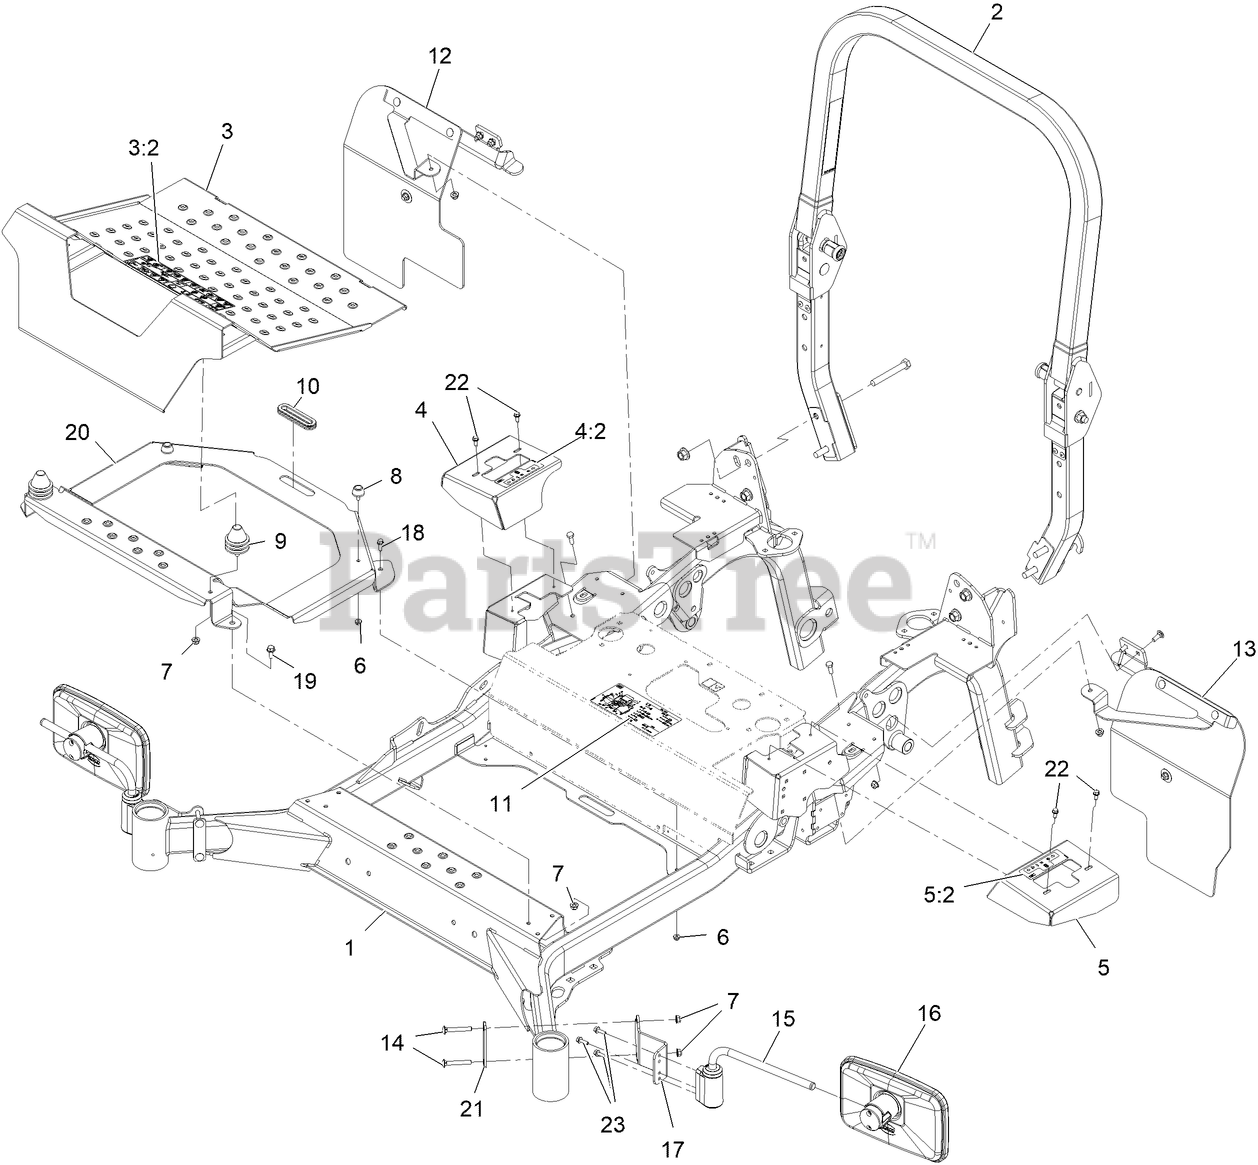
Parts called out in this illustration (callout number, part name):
1	MAINFRAME ASM, WD
2	ROPS ASM
3	PAN-FLOOR
3:2	DECAL-DANGER
4	ASM,MOTION CONTROL COVER W/DECAL RH
4:2	DECAL-RH MOTION CONTROL
5	ASM,MOTION CONTROL COVER W/DECAL LH
5:2	DECAL-LH MOTION CONTROL
7	NUT-HF, NI
8	BUMPER-RUBBER
9	ISOLATOR
10	GROMMET-RUBBER
11	DECAL-SERVICE AID
12	ASM, RH Mud Flap
13	ASM, LH Mud Flap
14	BOLT-CARR
15	MIRROR ARM
16	MIRROR, 144
17	PLATE-MIRROR MOUNT
18	SCREW-HHF
19	SCREW-HHF
20	BRACKET, FLOOR PAN RISER
21	BRACKET-MIRROR
22	SCREW-HWH
23	SCREW-HHF
